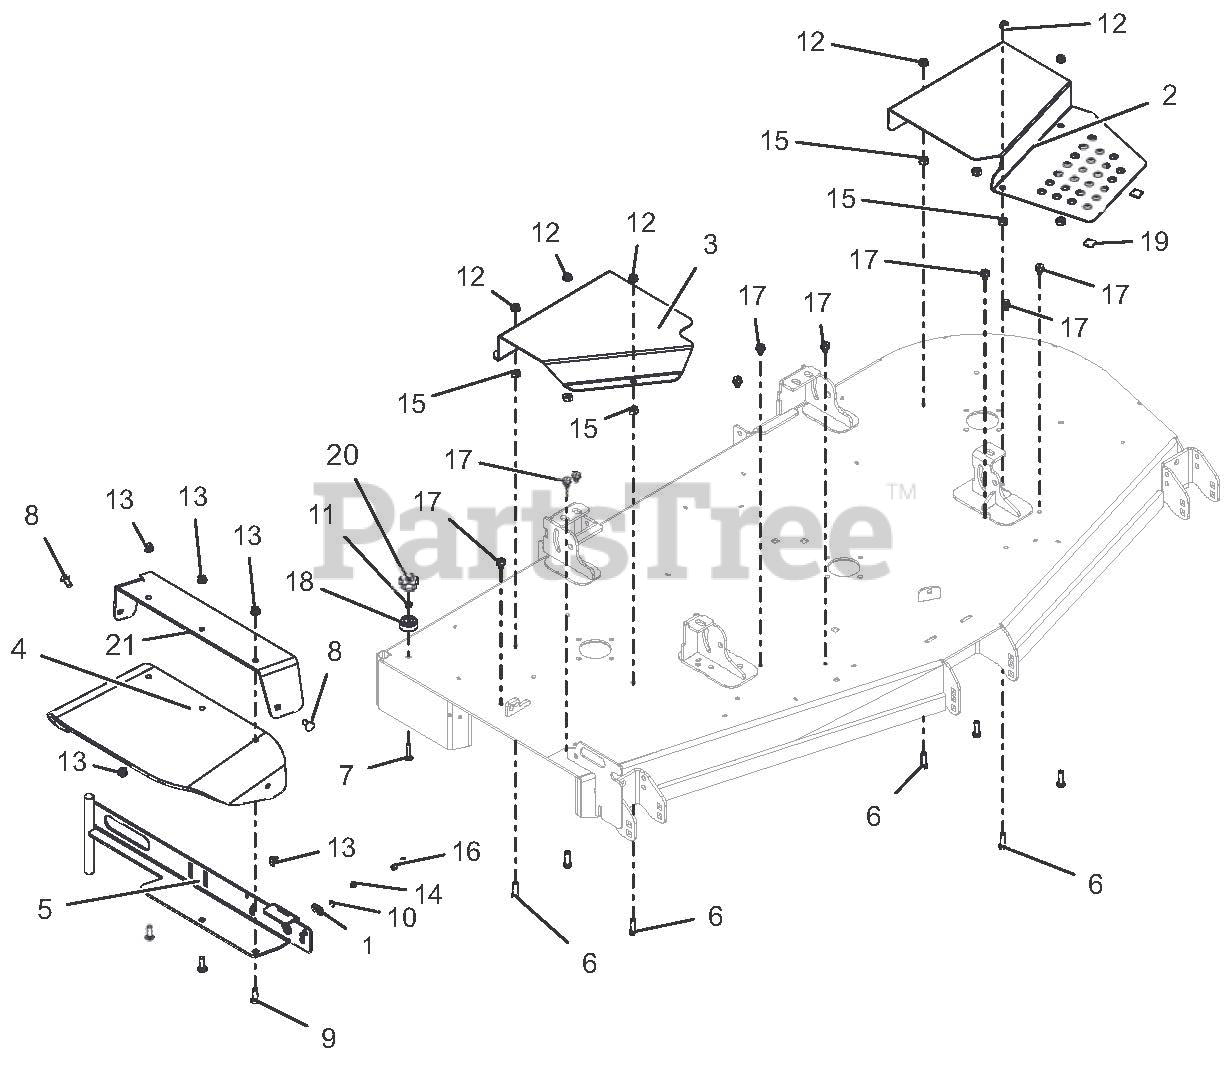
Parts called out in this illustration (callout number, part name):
1	KEEPER, BOLT
2	GUARD-72" LH DECK BELT W/STEP
3	72" RH DECK BELT GUARD - RED
4	CHUTE, RUBBER DISCHARGE
5	WMT, 66"-72" DISCH CHUTE MTG
6	@BLT-HEX .38-16X1.25 GR5 YWZC
7	@BLT-RDHDSQNK .31-18X1.50 G5YZ
8	@BLT-RDHDSQNK .38-16X1.00 G5YZ
9	@BLT-RDHDSQNK .38-16X1.25 G5YZ
10	@WSHR-LK-EXT.391X.628X.036YWZC
11	@NUT-LK-CTR .31-18 YWZC
12	@NUT-SPNLK-FLG .375-16 YWZC
13	@NUT-LK-NYL-FLG .38-16 YWZC
14	RVT-POP .187 YZ
15	NUT-HEAVY HEX .38-16 YWZC
16	BLT-HEX.38-16X1.25 GR5 CAP .37
17	@SCR-TAP .38-16X.50 HWH TR YWZ
18	BUMPER,RECESSED1.50X.63 W/.31
20	KNOB-CLAMPING, .312-18 NYLOC
21	DISCH CHUTE SUPPORT W/DECAL
